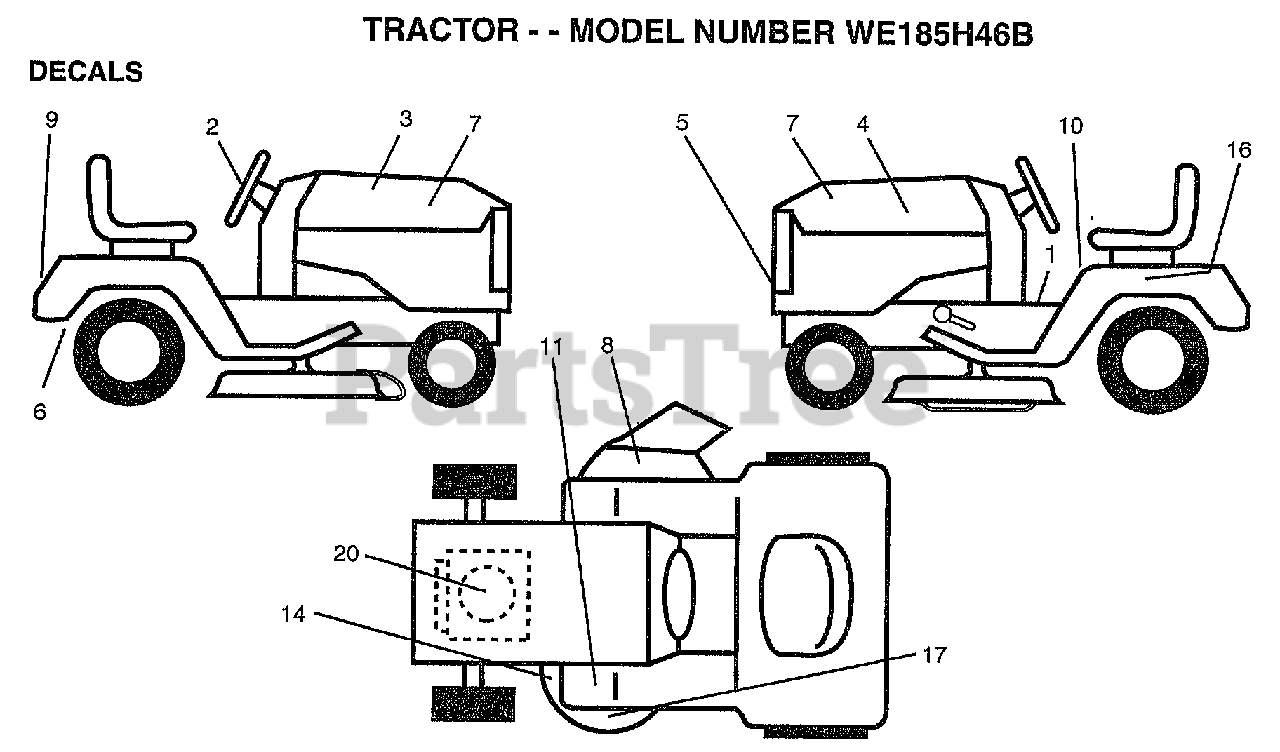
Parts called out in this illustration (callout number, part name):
1	DECAL SADDLE OPER
2	DECAL, INS STRG WH
3	DECAL.HOOD.RH.
4	DECAL.HOOD.LH
5	DECAL, GRILLE LENS
6	DECAL DRAWBAR LH
7	DECAL.PANEL.SIDE
8	"DECAL, WARNING"
9	DECAL.FENDER.LOGO
10	DECAL.CAUT.ENG/FR
11	DECAL T
14	"DECAL.V.BELT.44"""
16	DECAL.BATRY.3-3908
17	DECAL, DECK GRASSEATER
20	DECAL, HP, ENGINE
